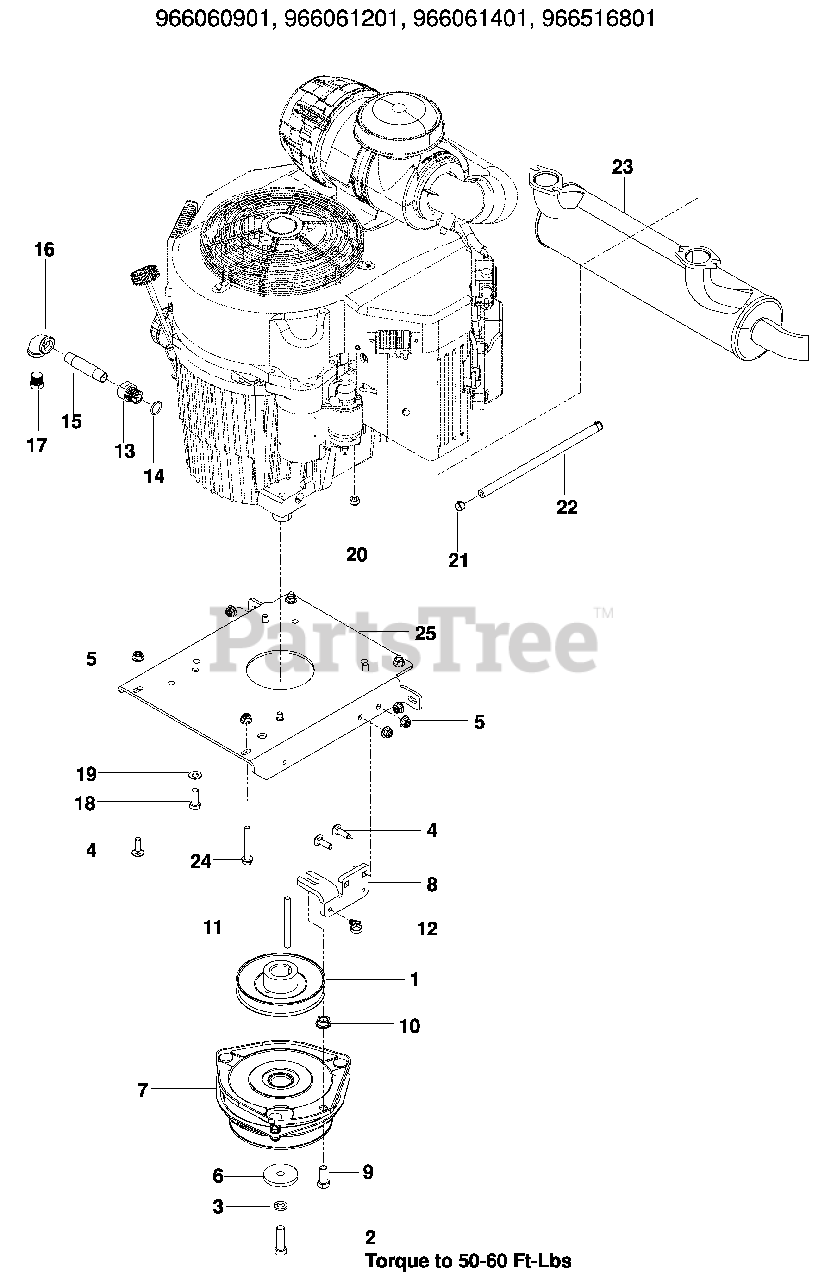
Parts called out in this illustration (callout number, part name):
1	PULLEY, ENGINE
2	BOLT 7/16-20 x 1½ HEX NYL
3	WASHER 7/16 SLW
4	BOLT 5/16-18 x 1 RD HD
5	NUT 5/16-18 HEX FLG NYLOC
6	WASHER, BLADE
7	CLUTCH, GT 3.5
8	STOP, CLUTCH
9	BOLT 7/16-14 x 1 HEX NYLOC
10	NUT 7/16-14 HEX WHIZ LK
11	KEY ¼ SQ x 3½
12	TIE WRAP w/ CLIP
13	ADAPTOR, OIL DRAIN
15	PIPE 3/8 NPT x 3"
17	PLUG, DRAIN, 3/8 NPTF
18	BOLT 3/8-16 x 1 HEX NYLOC
19	WASHER 3/8 SPRING
20	NUT M8X1.25 NYLOC
21	CLAMP, HOSE
22	FUEL LINE 5" 966060901
23	MUFFLER 966060901
24	SCREW 5/16-18 x 2¼ HEX FLG
25	PLATE, ENGINE
